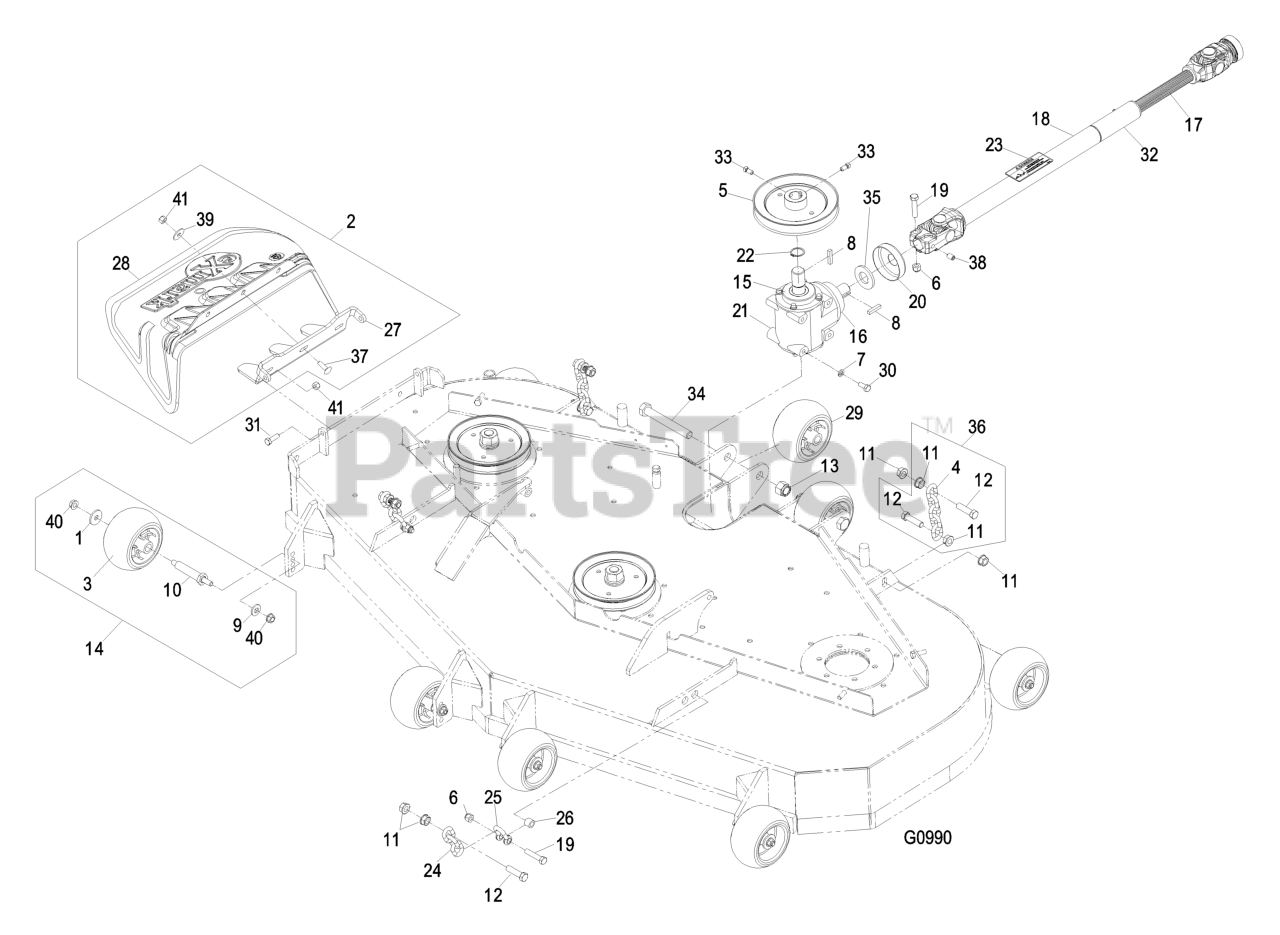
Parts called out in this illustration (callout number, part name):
3	ROLLER-SCALP, ANTI
4	CHAIN-LIFT, DECK
5	SHEAVE,6.88 ED B-SEC
6	NUT-LOCK, NI
7	WASHER-LOCK
8	KEY-SQUARE
9	WASHER-BELLEVILLE
12	SCREW-HH
13	NUT-LOCK, NI
19	SCREW-HH
20	GUARD,SEAL (PLTD)
21	GEARBOX,90 DEGREES
22	RING-RETAINING
23	DECAL-DRIVELINE
24	CHAIN-DECKLIFT
25	SHACKLE,FRONT CHAIN
26	BUSHING,SHACKLE
27	BRACKET,DISCHARGE CHUTE
28	CHUTE,DISCHARGE
29	ROLLER, FULL HUB
30	SCREW-HH
31	SCREW-HH
33	SCREW-SET
34	SCREW-HH
35	WASHER,SPECIAL
36	DECK CHAIN ASM
37	SCREW-CARR
38	SCREW-SET
39	WASHER-FLAT
40	NUT-HHF, WHIZ
41	NUT-LOCK, NI
